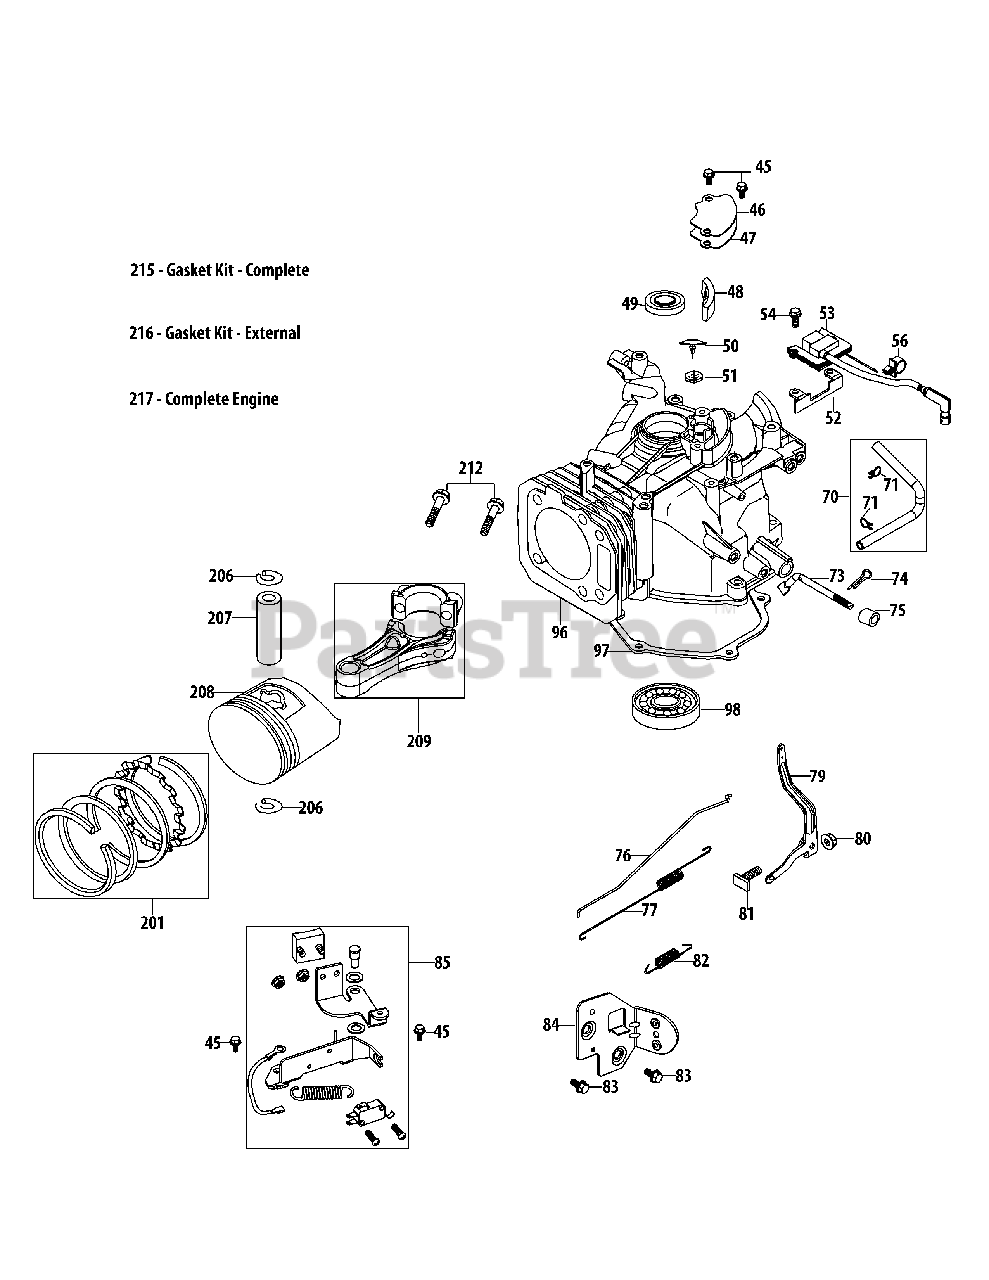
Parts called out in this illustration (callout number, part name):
45	Bolt M6X14
46	Breather Cover Plate
47	Breather Gasket
48	Breather Screen
49	Upper Crankshaft Seal
50	Breather Valve
51	Breather Valve Base
52	Ignition Coil Bracket
53	Ignition Coil Assembly
54	Bolt M6X18
56	Ignition Wire Clip
70	Breather Hose Assembly
71	Breather Hose Clamp
73	Governor Arm Shaft
74	Governor Shaft Arm Cotter Pin
75	Governor Seal
76	Throttle Linkage
77	Throttle Linkage Spring
79	Governor Arm
80	Governor Arm Nut M6
81	Governor Arm Bolt
82	Governor Spring
83	Bolt M6X12
84	Primer Bracket
85	Brake Assembly
96	Short Block Assembly
97	Crankcase Cover Gasket
98	Main Bearing
201	Piston Ring Set
206	Piston Pin Snap Ring
207	Piston Pin
209	Connecting Rod Assembly
212	Connecting Rod Bolt
215	Gasket Kit - Complete
216	Gasket Kit - External
217	Complete Engine
